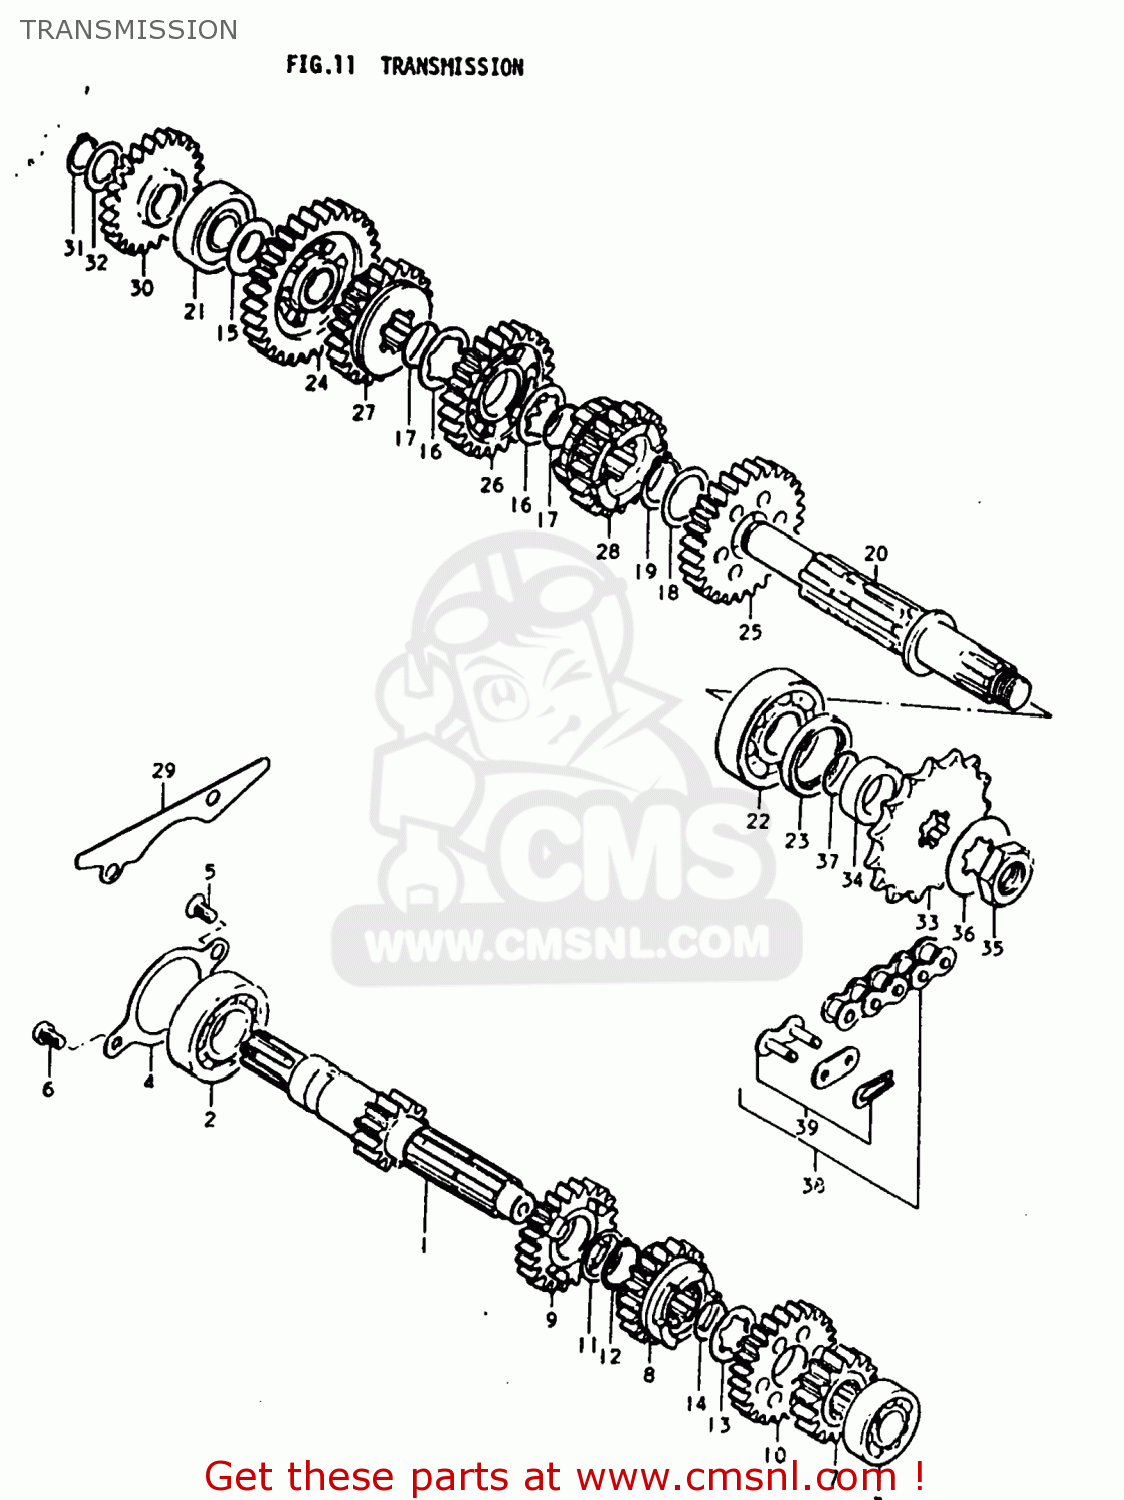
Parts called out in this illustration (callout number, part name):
1	SHAFT,COUNTER
2	BEARING
3	BEARING
4	PLATE,COUNTERSHAFT BEARING
5	SCREW
6	SCREW 6X12
7	GEAR,SECOND DRIVE
8	GEAR,THIRD DRIVE
9	GEAR,FOURTH DRIVE
10	GEAR,FIFTH DRIVE
11	SHIM
12	CIRCLIP
13	WASHER,LOCK
14	CIRCLIP
15	WASHER,THRUST
16	WASHER,LOCK
17	RING,SNAP
18	WASHER
19	CIRCLIP
20	SHAFT,DRIVE
21	BEARING
22	BEARING
23	SEAL,OIL(32X42X6)
24	GEAR,FIRST DRIVEN
25	GEAR,SECOND DRIVEN
26	GEAR,THIRD DRIVEN
27	GEAR,FOURTH DRIVEN
28	GEAR,5TH DRIVEN
29	PLATE,OIL RESERVOIR
30	GEAR,KICK STARTER IDLE
31	CIRCLIP
32	WASHER
33	SPROCKET,ENGINE
34	SPACER(22X32X11.5)
35	NUT
36	WASHER,LOCK
37	O RING(D:1.7,ID:22)
38	CHAIN,DRIVE #525TR-10
39	JOINT ASSEMBLY,CHAIN
